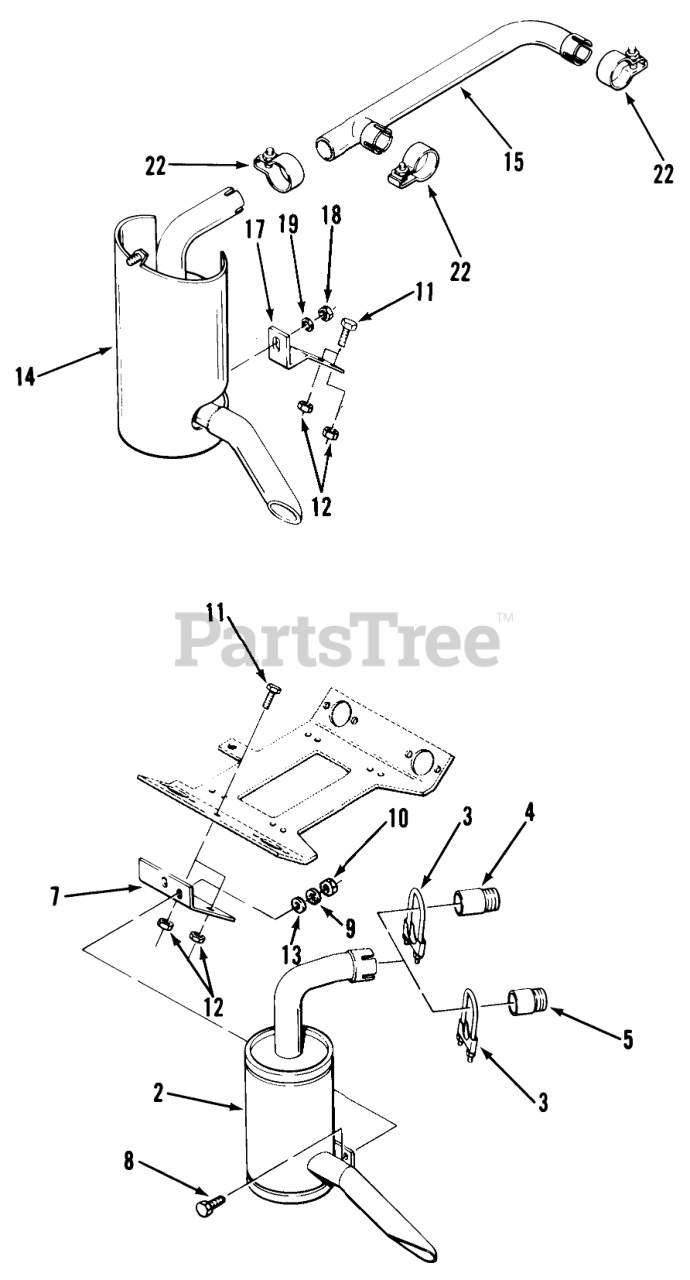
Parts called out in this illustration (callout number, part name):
2	MUFFLER ASSEMBLY
3	ASSY-MUFFLER CLAMP
4	NIPPLE
5	NIPPLE- 1X2 SPECIAL
7	BRACKET-MUFFLER MTG
8	H H C S
9	Washer
10	Nut
11	Bolt
12	Nut
14	Muffler C-175 Twin Only
15	MANIFOLD-EXHAUST
17	BRACKET-MUFFLER
18	Nut
19	LOCKWASHER
22	CLAMP-MUFFLER
